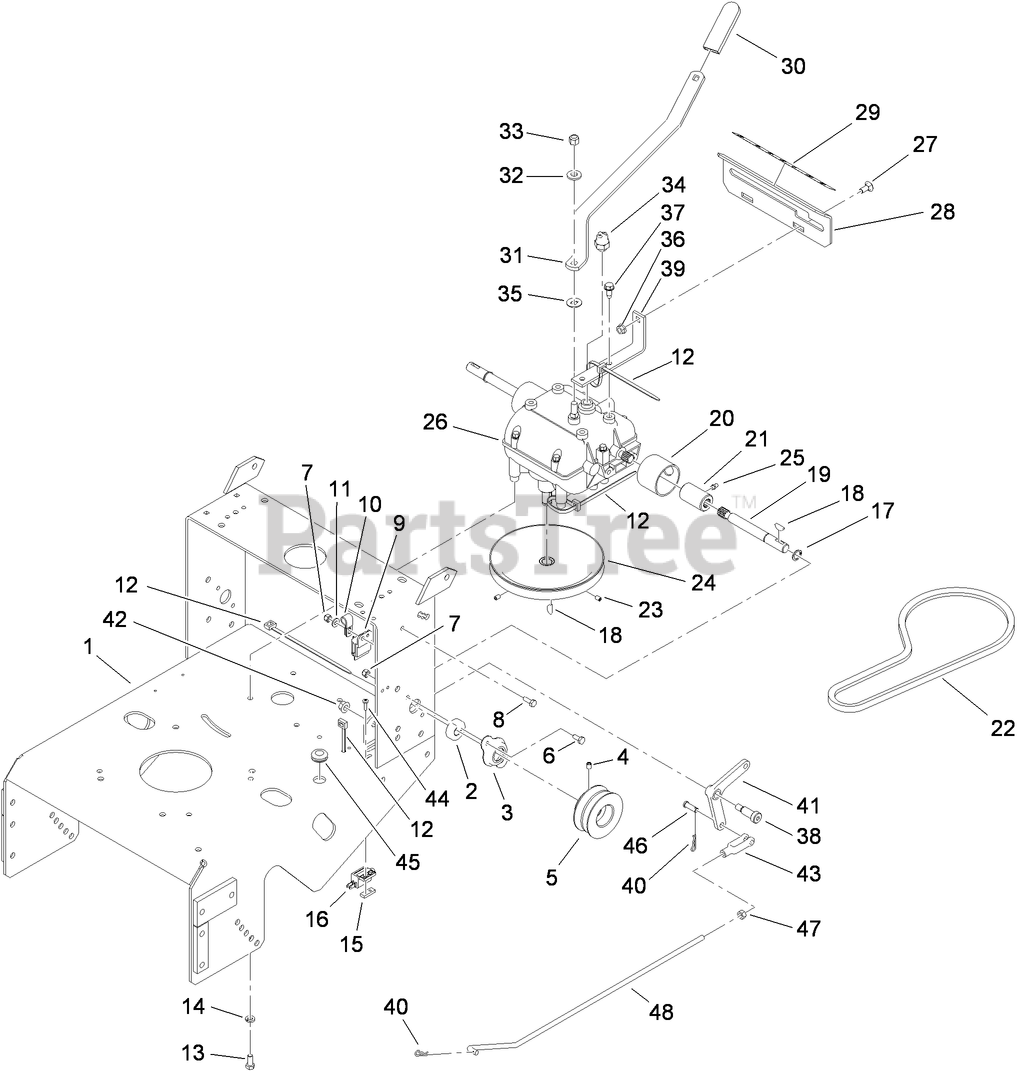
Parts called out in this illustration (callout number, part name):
1	GEAR FRAME ASM
2	BEARING-SHAFT
3	FLANGE-OUTPUT
4	SCREW-SET
5	SHEAVE-TRANSMISSION
6	SCREW-HH
7	NUT-LOCK, NI
8	SCREW-HH
9	MODULE-INTERLOCK
10	CLIP-LOOM
11	WASHER-FLAT
12	TIE-PLASTIC
13	SCREW-HH
14	WASHER-LOCK
15	PLATE-TAPPED
16	SWITCH-OPEN, NORMALLY
17	RING-RETAINING
18	KEY-WOODRUFF
19	SHAFT-TRANSMISSION
20	GUARD-COUPLER
21	COUPLER
22	V-BELT
23	SCREW-HSH
24	SHEAVE-TRANSMISSION
25	FITTING-GREASE
26	TRANSMISSION
27	BOLT-CARR
28	PLATE-SHIFT
29	DECAL-SPEED, GROUND
30	GRIP-LEVER
31	LEVER-SHIFT
32	WASHER-BELLEVILLE
33	NUT-LOCK
34	Switch-Start, Neutral
35	WASHER
36	NUT-HF
37	SCREW-HWH, THREAD CUT
38	BOLT-SHOULDER
39	BRACKET-PLATE, SHIFT
40	PIN-COTTER
41	BELLCRANK
42	NUT-HF
43	YOKE-ADJUSTABLE
44	SCREW-PPH
45	GROMMET
46	PIN-CLEVIS
47	NUT-HEX
48	ARM-ASSIST, LINKAGE
